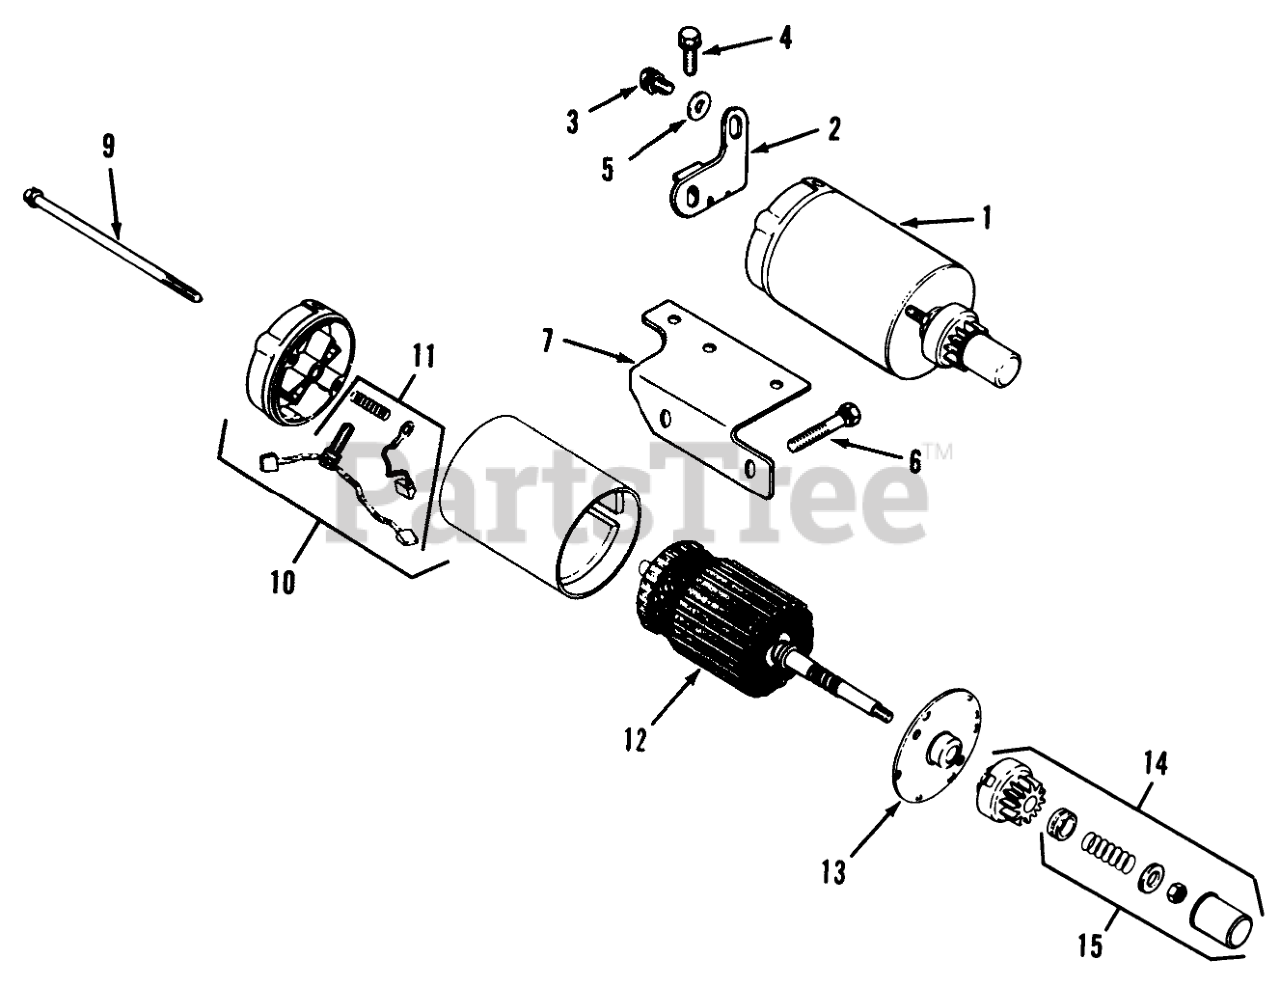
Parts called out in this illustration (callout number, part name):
1	KOHLER 41-098-04
2	KOHLER 45-126-17
3	KOHLER X-67-62
4	KOHLER X-67-83
5	KOHLER X-25-78
6	KOHLER X-159-2
7	KOHLER 47-126-29
9	KOHLER 41-086-19
10	KOHLER 41-227-04
11	VNDR #52-755-15
12	KOHLER 47-170-02
13	KOHLER 41-227-03
14	KOHLER 47-755-07
15	KOHLER 47-755-13
